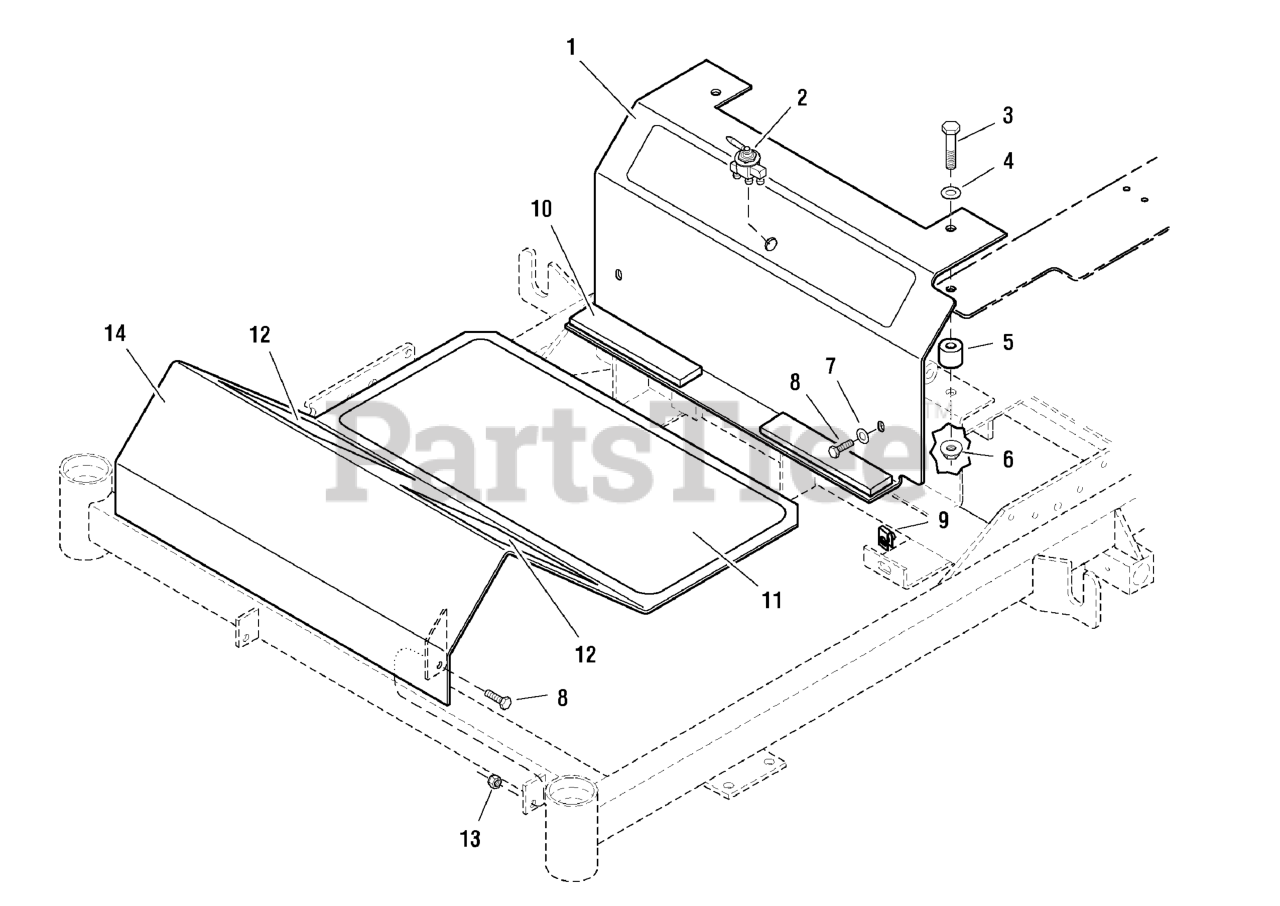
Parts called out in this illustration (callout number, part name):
1	BRAKE COVER PANEL ASSEMBLY
2	VALVE, Fuel Shut Off
3	BOLT, 3/8-16 X 2, GD5, CZ
4	WASHER, 3/8 SAE
5	SPACER, .39 x 1.00 x .88
6	NUT, 3/8-16 Hex Serrated Flange
7	WASHER, 5/16" SAE
8	BOLT, 5/16-18 X 1 GD5 YZ
9	BODY CLIP, 5/16-18-7GA MATERIAL
10	RUBBER PAD
11	SAFETY WALK, 11.50 X 19.00
12	SAFETY WALK
13	NUT, 5/16-18 Hex Nylon Lock
14	FLOOR PLATE
